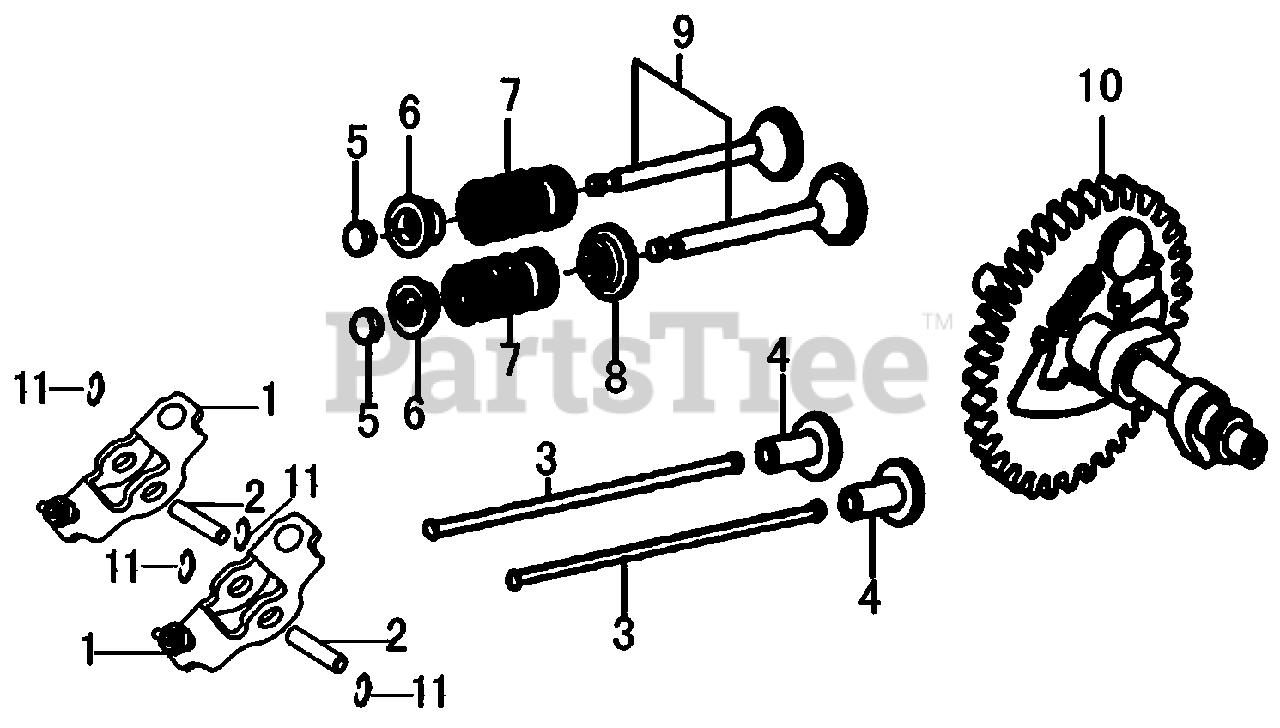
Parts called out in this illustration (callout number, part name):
1	ARM, ROCKER
2	SHAFT, VALVE ROCKER
3	ROD, PUSH
4	LIFTER VALVE
5	ROTATOR, VALVE
6	RETAINER, VALVE SPRING
7	SPRING, VALVE
8	SEAL, GUIDE
9	VALVE SET
10	CAMSHAFT ASSY.
11	SPLIT WASHER
